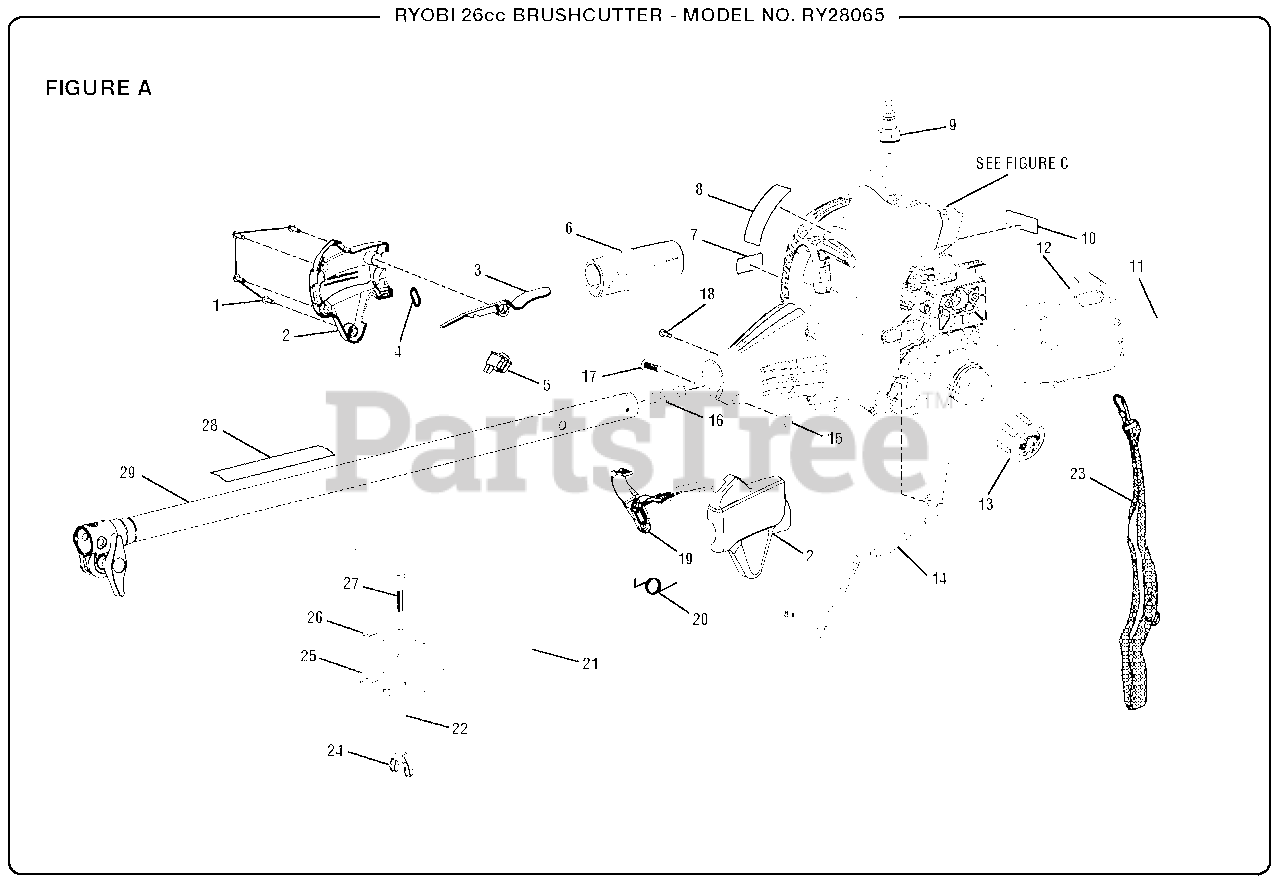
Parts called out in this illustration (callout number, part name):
1	Screw (M4 x 20 mm)
2	Control Handle Assembly
3	Trigger Lock
4	Strap Hanger
5	Switch (Momentary Contact)
6	Rear Handle
7	Combustion Warning Label
8	Logo Label
9	Spark Plug (Champion RCJ6Y)
10	Model Label (BC26)
11	Starting Label
12	Air Box Cover
13	Fuel Cap Assembly (1.5 in. Diameter)
14	Throttle and Lead Assembly
15	Hex Nut (M6)
16	Compression Spring
17	Bolt (M6 x 20 mm)
18	Screw (8-16 x 5/16 in., Torx T.F.)
19	Throttle Trigger
21	J" Handle and Grip
23	Shoulder Harness
24	Wing Nut (1/4-20)
25	Bottom "J" Handle Clamp
26	Top "J" Handle Clamp
27	Bolt (1/4-20 x 1-1/2 in., Hex Hd.)
28	Warning Decal
29	Upper Boom Assembly
